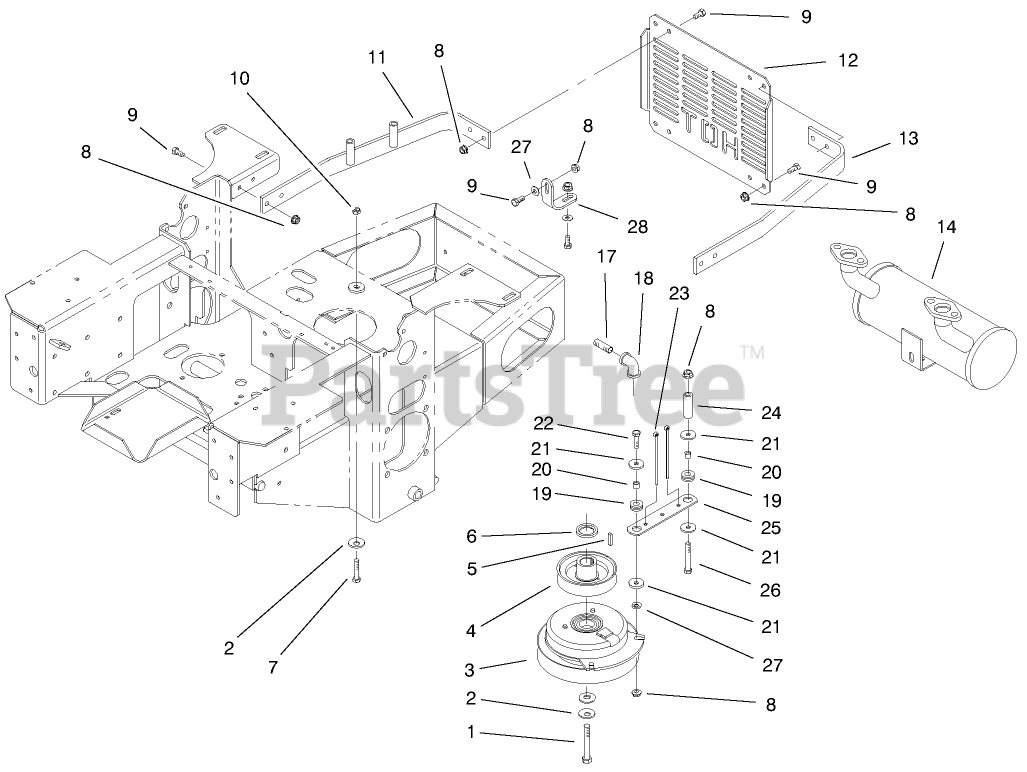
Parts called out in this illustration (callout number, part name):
1	SCREW-HH
2	Disc-Spring
3	Clutch
4	Sheave-Pump Drive
5	Key
6	Spacer-Crankshaft
7	SCREW-HH
8	NUT-LOCK, NI
9	SCREW-HH
10	NUT-HF
11	Strap-Guard, Engine
12	Shield-Guard, Engine
13	Strap-Guard, Engine
14	Muffler
17	Pipe Nipple
18	Elbow
19	Grommet
20	Spacer
21	Washer
22	SCREW-HH
23	Tie-Plastic
24	Bushing-Mount, Seat
25	Strap
26	SCREW-HH
27	WASHER-FLAT
28	Bracket-Muffler
